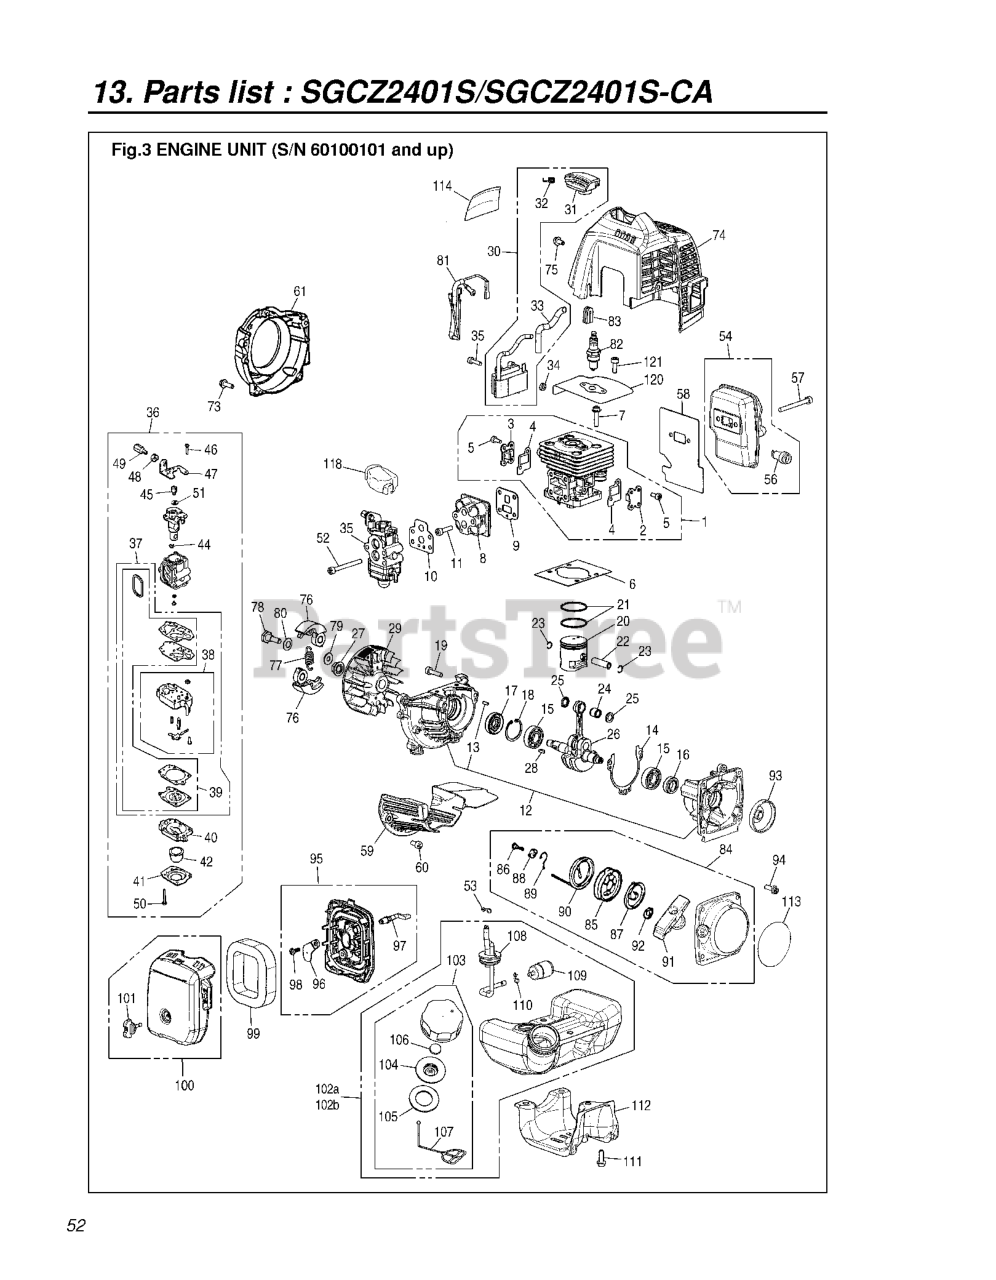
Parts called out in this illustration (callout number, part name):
1	CYLINDER COMPLETE
2	COVER, TR-S
3	COVER, TR-F
4	GASKET, TR
5	BOLT
6	GASKET, BASE
7	BOLT
8	INSULATOR
9	INSULATOR GASKET(R-848F0814B0)
10	GASKET, CARB
11	BOLT TORX
12	CRANKCASE-C
13	PIN
14	GASKET, CASE
17	SEAL
22	PIN
26	CRANKSHAFT-C
27	NUT
28	KEY
30	COIL ASSY
31	CAP
34	SPACER
36	CARBURETOR (RPLS 848F088100)
37	REBUILD KIT
38	CARBURETOR BODY
39	GASKET KIT
41	1OVER
44	RING
45	SWIVEL
46	SCREW
47	BRACKET
48	NUT
49	ADJUSTER
51	WASHER
53	CLIP
54	MUFFLER-A***
56	ARRESTER
58	GASKET, MUFFLER
74	COVER, ENGINE
75	BOLT (RPLS T495051010-11)
81	CORD-COMP
82	PLUG CMR7H
84	RECOIL ASSY
87	SPRING, SPIRAL
88	COLLAR
89	SWING ARM
92	PLATE.STOPPER
95	BODY ASSY
96	PLATE.CHOKE
97	LEVER CHOKE
98	SCREW
100	COVER-A (RPLS T155182200)
102A	TANK ASSY (RPLS T155185001)
103	CAP A
104	HOLDER-A
108	PIPE-C
109	FILTER ASSY
110	CLIP
114	LABEL COVER
